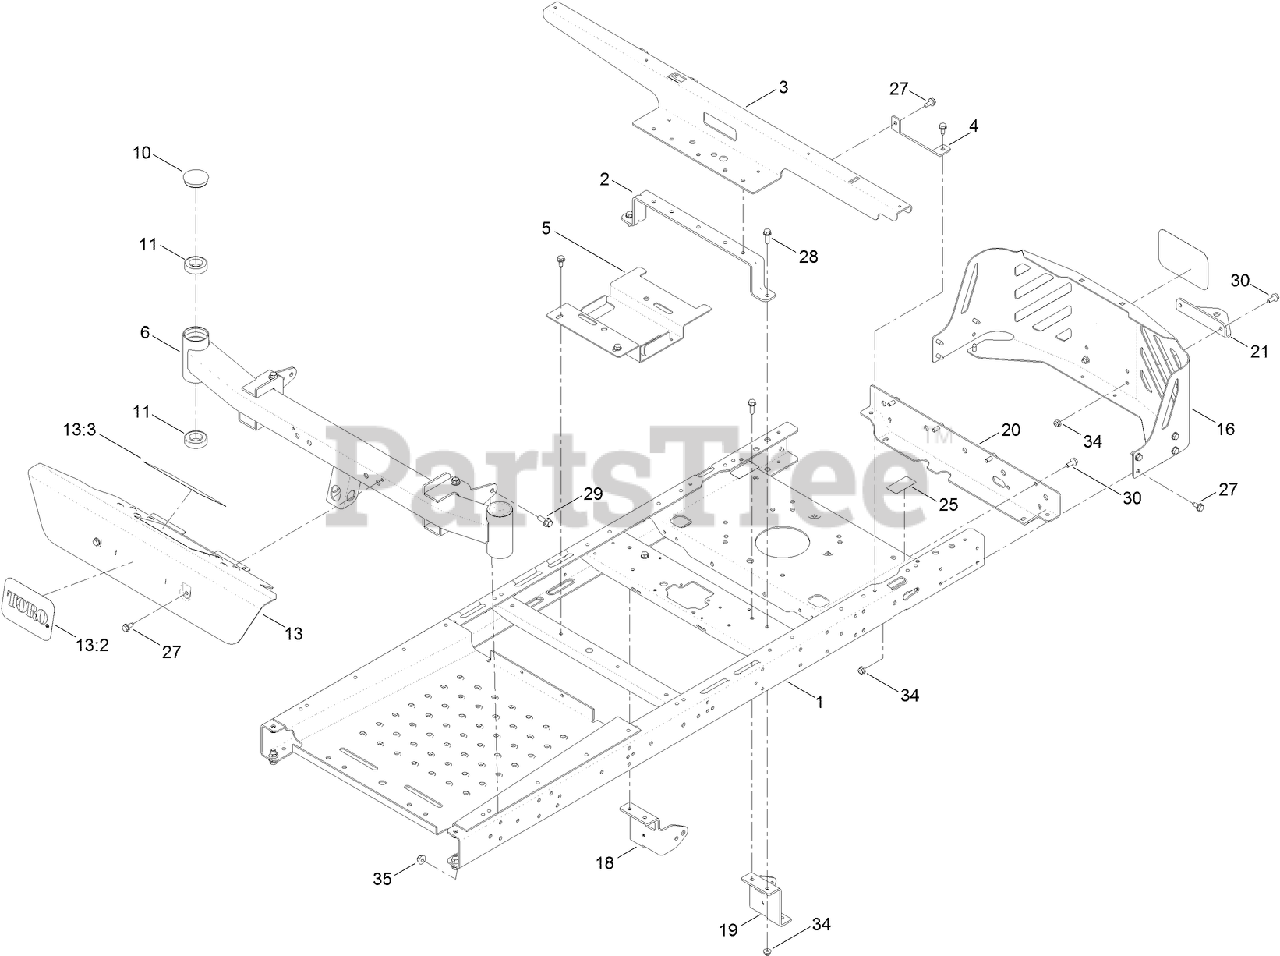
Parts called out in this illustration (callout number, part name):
1	FRAME ASM
2	BRACE-SEAT, REAR
3	SUPPORT-POD, WIDE
4	SUPPORT-TANK, REAR
5	BRACKET-BATTERY
6	AXLE ASM
10	CAP-GREASE
11	BEARING-BALL
13	FOOTREST ASM
13:2	DECAL
13:3	DECAL-DANGER
16	GUARD-ENGINE, WIDE
18	MOUNT-HYDRO, FRONT (RH)
19	MOUNT-HYDRO, FRONT (LH)
20	CROSSMEMBER-REAR, WIDE
21	BRACKET-HITCH
25	DECAL-BYPASS
27	SCREW-HWHTF
28	SCREW-HHF
29	SCREW-HHF
30	SCREW-HHF
34	NUT-HF, NI
35	NUT-HF, NI
